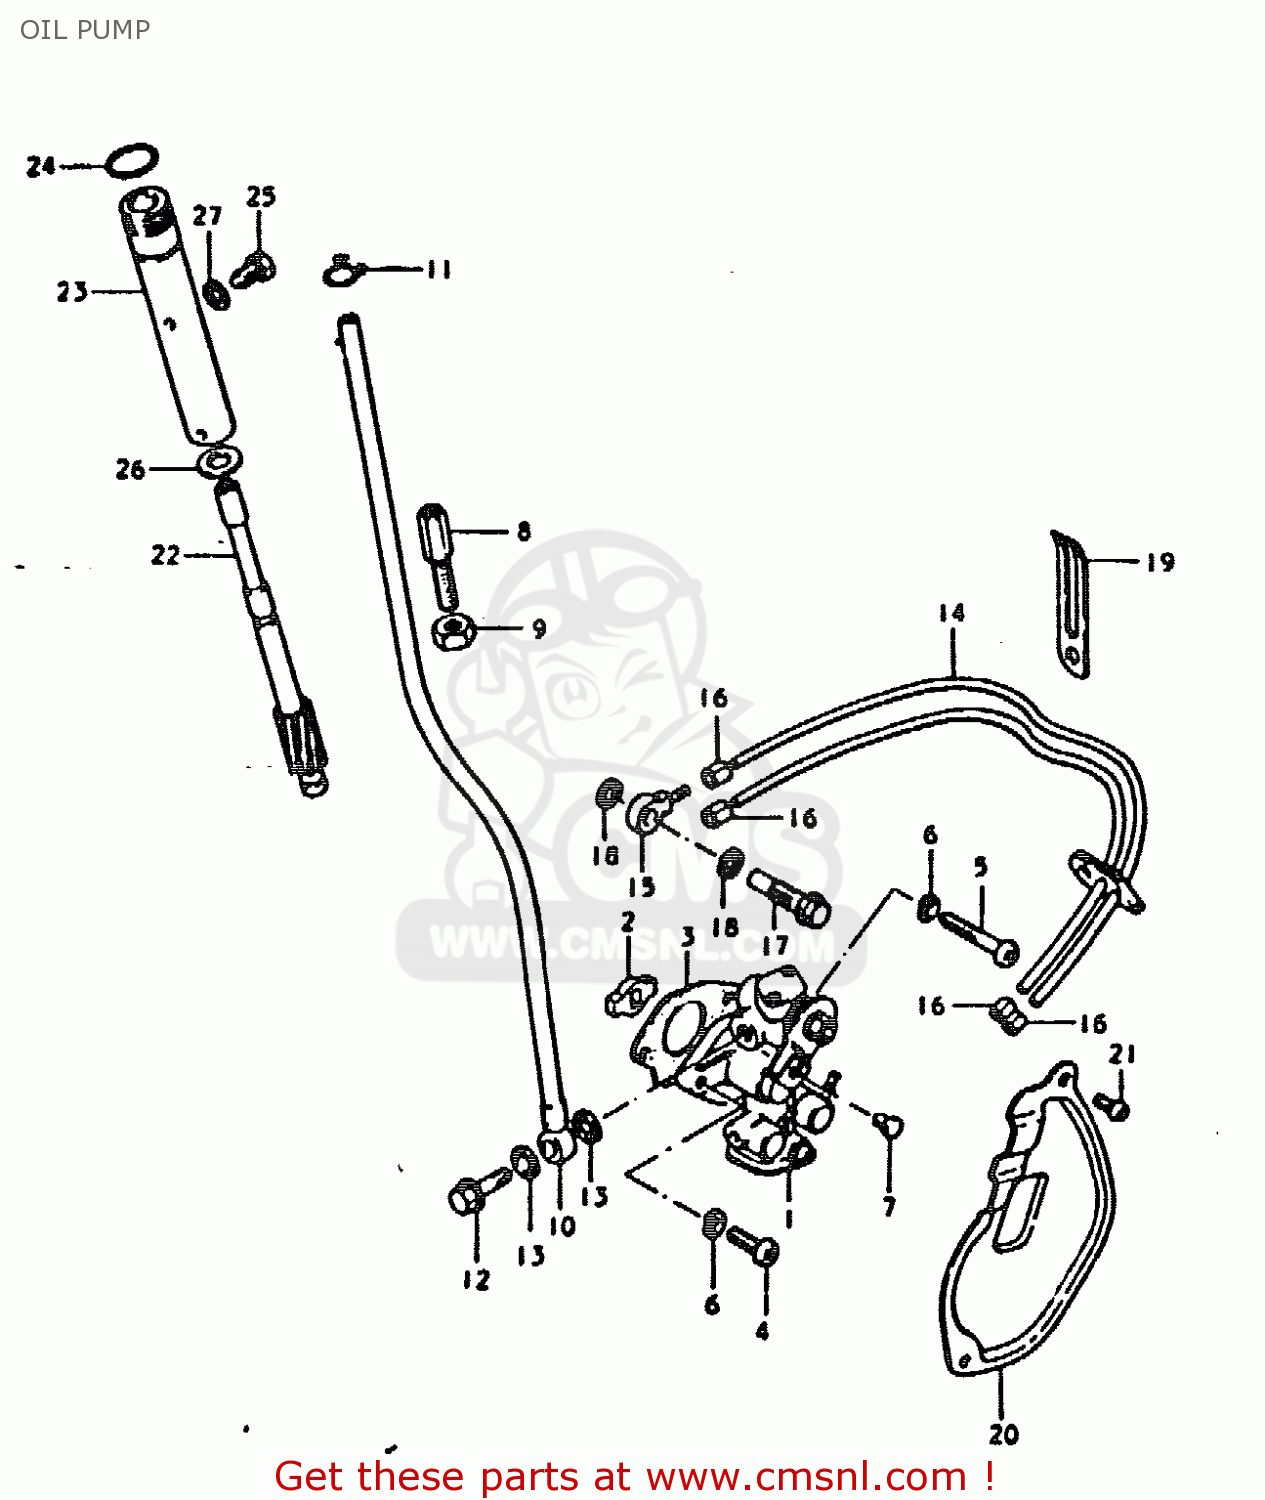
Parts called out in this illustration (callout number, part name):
1	PUMP ASSEMBLY,OIL
2	PIECE,OIL PUMP DRIVE
3	GASKET,OIL PUMP (NAS)
4	SCREW
5	SCREW
6	LOCK WASHER
7	TERMINAL,CABLE
8	BOLT
9	NUT
10	HOSE,OIL NO.1
11	CLIP
12	UNION BOLT
13	GASKET(6.2X11X1).2 (NAS)
14	HOSE,OIL NO.2
15	UNION
16	CLIP
17	UNION
18	GASKET(6.2X11X1).2 (NAS)
19	CLAMP L:35
20	CAP,OIL PUMP INSPECTION
21	SCREW
22	GEAR,TACHOMETER DRIVEN
23	SLEEVE,TACHOMETER DRIVE
24	O RING(D:1.3,ID:9.6)
25	BOLT(6X12)
26	WASHER(8X13.7X1)
27	WASHER
